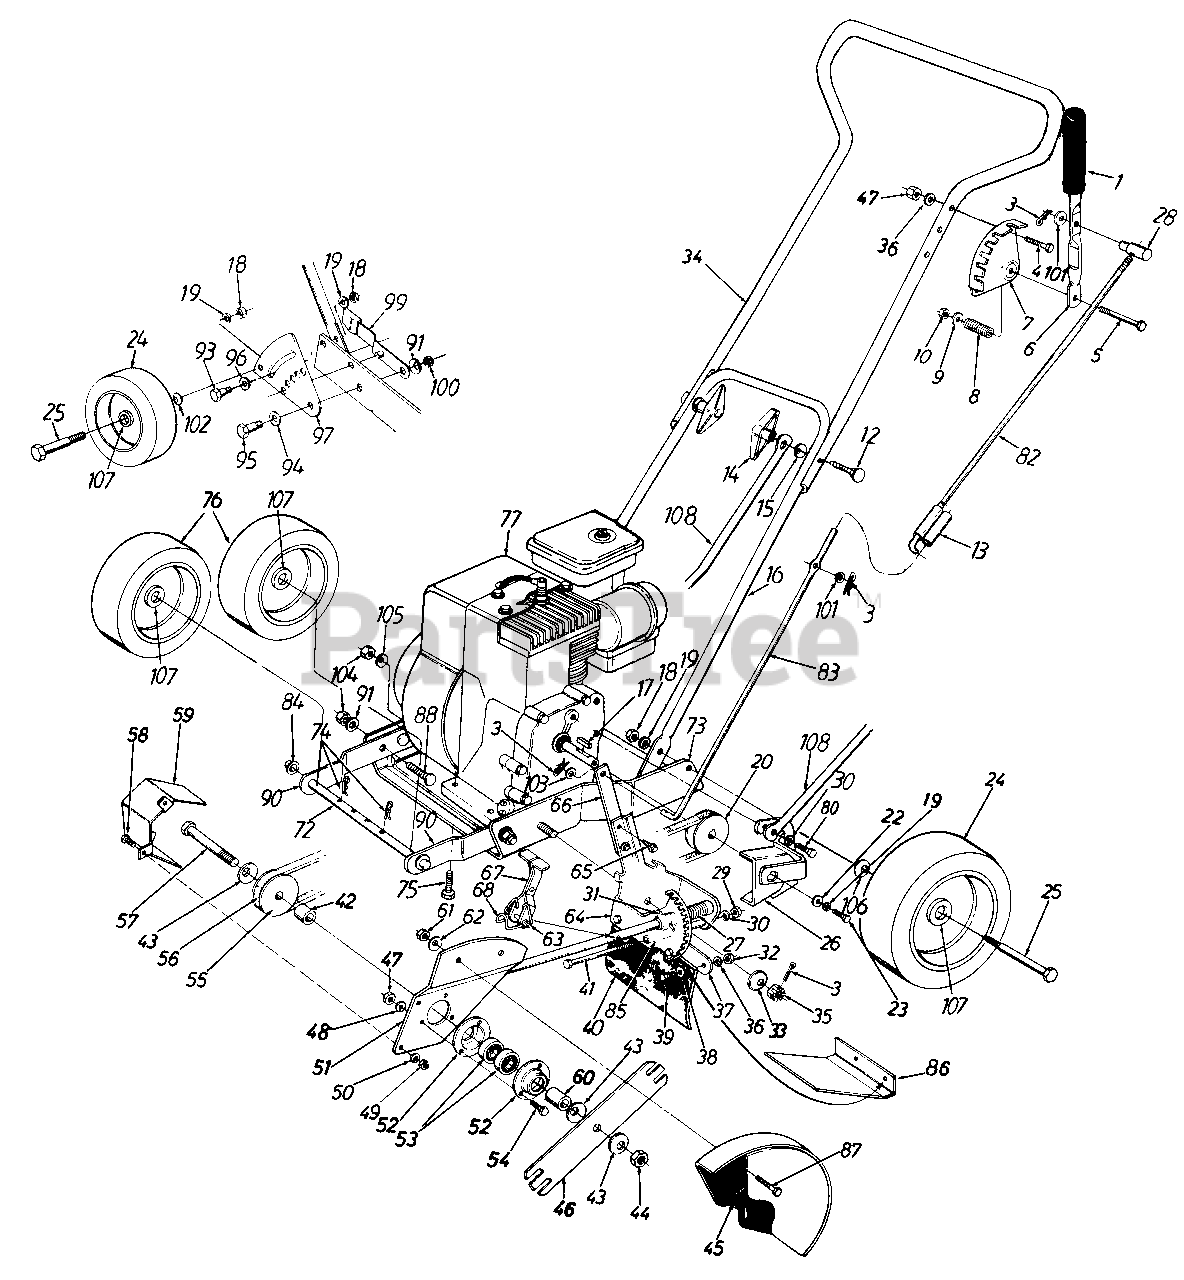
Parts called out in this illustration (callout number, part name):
3	Cotter Pin 5/16" Dia.
4	Hex Bolt 1/4-20 x 1.25" Lg.
5	Hex Bolt 5/16-18 x 2" Lg.
8	Compression Spring 1.38" Lg.
9	Fl-Wash. .344" I.D.
10	Hex L-Nut 5/16-18 Thd.
12	Curv. Hd. Bolt 5/16-18 x 2" Lg.
13	Clutch Rod Lock
14	Wing Nut Ass'y.
15	Saddle Wash. .32" I.D. x .937"
18	Hex Nut 3/8-16 Thd.
19	L-Wash. 3/8" I.D.
20	Engine Pulley
22	Fl-Wash. .385" I.D.
23	Hex Bolt 3/8-24 x 1" Lg.
24	Rear Wheel Ass'y.
25	Shoulder Bolt .498" Dia.
28	Ferrule
29	Hex Nut 5/16-18 Thd.
30	L-Wash. 5/16" I.D.
31	Spring Pin Spir. 1/4" Dia.
32	Hex Nut 1/4-20 Thd.
33	Bell-Wash. .535" I.D.
34	Upper Loop Handle
35	Hex Slotted Nut 1/2-20 Thd.
36	L-Wash. 1/4" I.D.
37	Flap Bracket
38	Fl-Wash. .25" I.D.
39	Hex Bolt 1/4-20 x .62" Lg.
41	Hex Bolt 5/16-18 x 4.5" Lg.
42	Spacer 1.030" Lg.
43	Bell-Washer. .63" I.D.
44	Hex Jam L-Nut 5/8-18 Thd.
47	Hex Nut 1/4-20 Thd.
48	L-Wash. 1/4" I.D.
49	Hex Nut 1/4-20 Thd.
50	L-Wash. 1/4" I.D.
53	Ball Bearing .62" 1 .D.
54	Hex Bolt 1/4-20 x .62" Lg.
55	3/8" "V"-Pulley
56	"V"-Belt
57	Hex Bolt 5/8-18 x 4.5" Lg.
58	Hex Bolt 1/4-20 x .625" Lg.
60	Sleeve .90" Lg.
61	Hex Nut 5/16-18 Thd.
62	Bell-Wash. .345" I.D.
63	Spring Pin Spir. 1/4" Dia.
68	Torsion Spring
72	Axle 8.20" Lg. (Front)
75	Hex L-Wash. TT-Tap Scr. 3/8-16 x 1" Lg.
76	Front Wheel Ass'y.
77	Engine
80	Hex Bolt 5/16-24 x .62" Lg.
82	Upper Clutch Rod
83	Lower Clutch Rod
84	Push Cap 1/2" Dia.
85	Spacer 3.765" Lg.
88	Ribbed Neck Bolt 3/8-24 x .8" Lg.
93	Shld. Bolt .5" Dia.
94	Bell-Wash. .515" I.D.
95	Shld. Bolt .50" Dia.
96	Fl-Wash. .51" I.D. x .94"
100	Hex Jam Nut 3/8-16 Thd.
101	Fl-Wash. .344" I.D. x .62" O.D.
102	Wave Wash. .51" I.D.
103	Fl-Wash. .406" I.D. x .81" O.D.
104	Hex Nut 3/8-24 Thd.
105	Bell-Wash. .396" I.D. x 1.14" O.D.
106	Wave Wash. .51" I.D.
107	Ball Bearing
